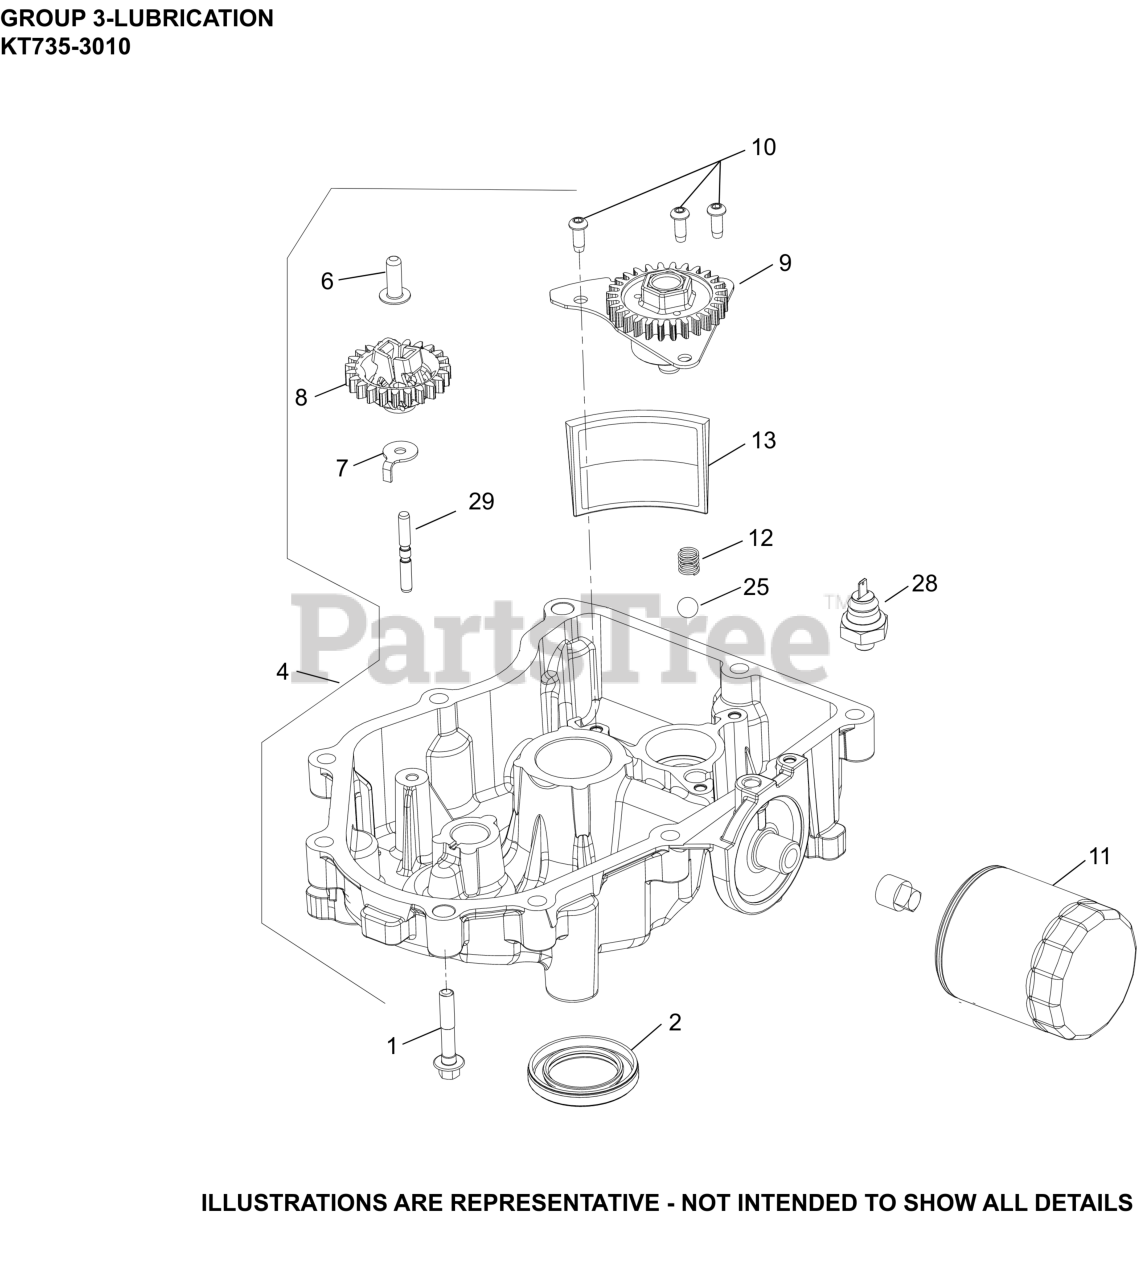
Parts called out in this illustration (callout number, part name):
1	SCREW, FLG M8X1.25X45
4	OIL PAN ASSEMBLY, (ROLLER BURNISHED)
6	PIN, GOVERNOR REGULATING
7	TAB, LOCKING
8	KIT, GOVERNOR GEAR
9	PUMP ASSEMBLY, OIL
10	SCREW, BUTTON HEAD
11	OIL FILTER
12	SPRING, COMPRESSION
13	SCREEN, OIL
25	PRESSURE RELIEF BALL
28	SWITCH, OIL PRESSURE(NC 3-6 PSI TO OPEN)
29	SHAFT, GOVERNOR GEAR
NI	PLUG, PIPE CTSK 3/8"
